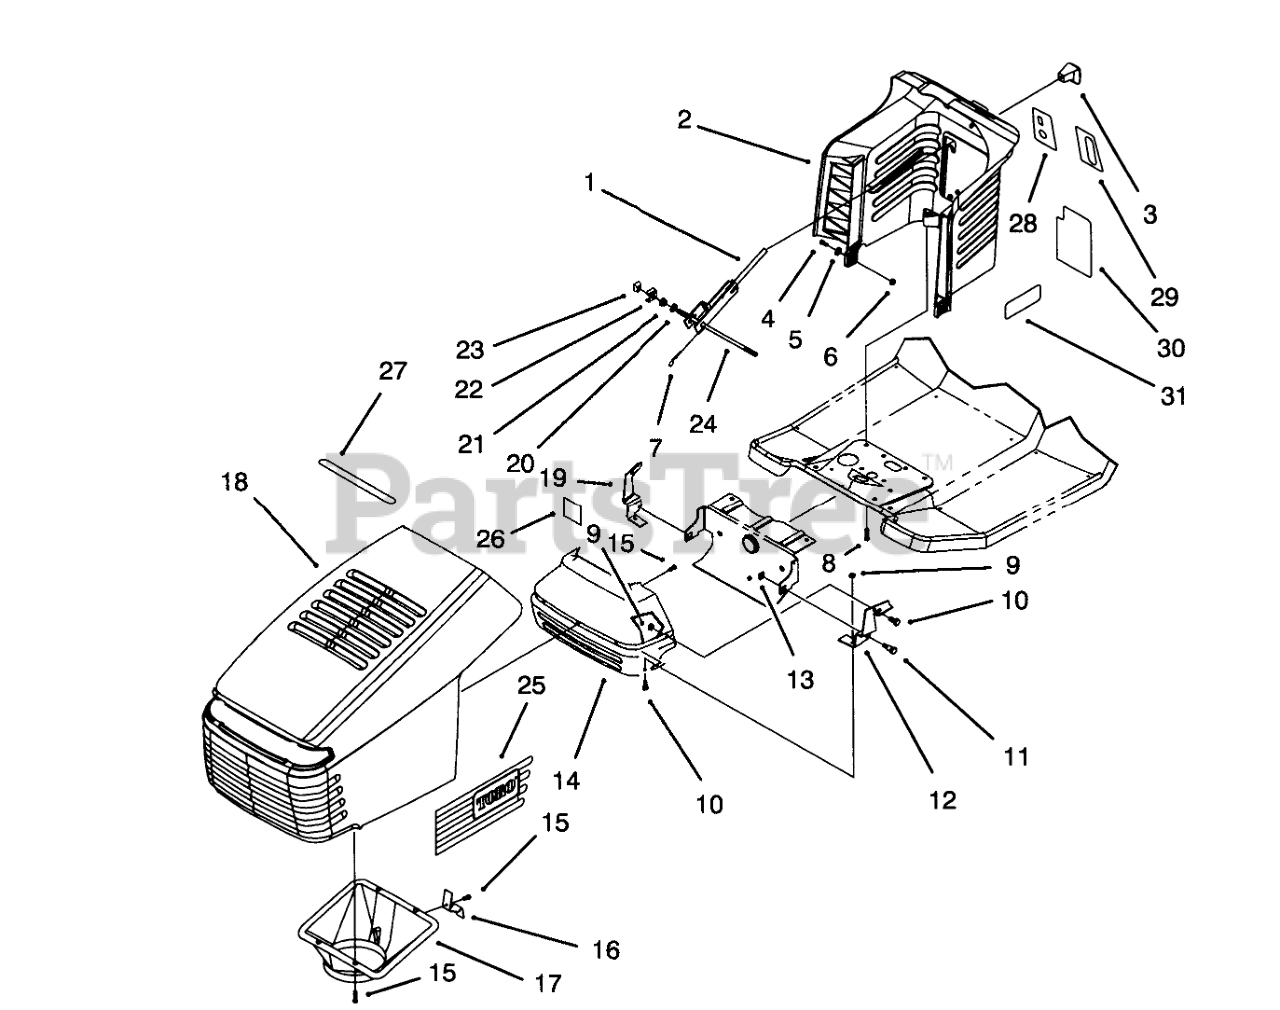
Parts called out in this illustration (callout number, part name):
1	Lever-Deck Engage
2	Tower-Steering
3	SHIFT KNOB
4	SCREW-HH
5	WASHER-PLAIN
6	NUT-LOCK, NI
7	PIN-COTTER
8	SCREW-HWH
9	NUT-LOCK, NI
10	SCREW-HH
11	BOLT-SHOULDER
12	Bracket-Hinge L.H.
13	NUT-RETAINER
14	Shield-Heat
15	SCREW-PLASTITE
16	HOOD LATCH
17	DUCT-AIR
18	HOOD ASM
19	Bracket-Hinge R.H.
20	WASHER-FLAT
21	NUT-FLANGE
22	ROD-CLAMP PIVOT
23	NUT-WEDGE
24	ROD-TOWER PIVOT
25	DECAL - HOOD RIGHT
26	TAPE-FOIL
27	DECAL-AIR DUCT
28	DECAL-IGNITION/LIGHTS
29	DECAL
30	DECAL-DECK, ENGAGE
31	DECAL - TOWER
